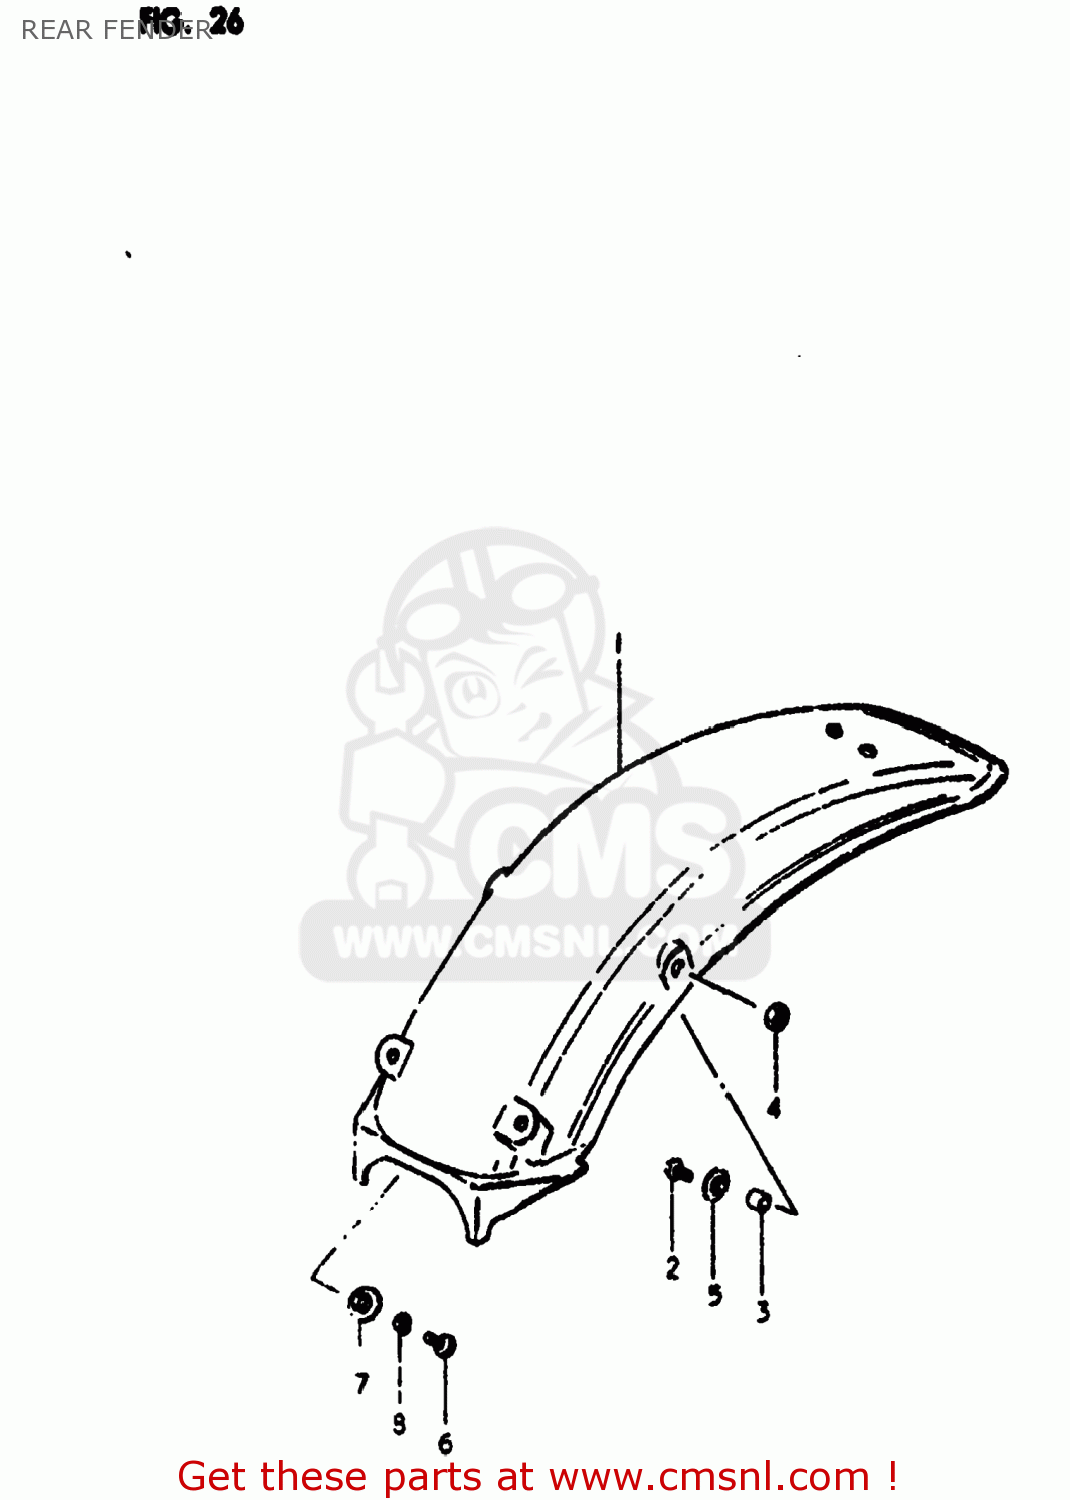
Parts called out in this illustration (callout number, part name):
1	FENDER,REAR
2	SCREW
3	SPACER
4	NUT
5	WASHER (6.5X20X1.2)
6	BOLT, UPPER
7	WASHER
8	LOCK WASHER
